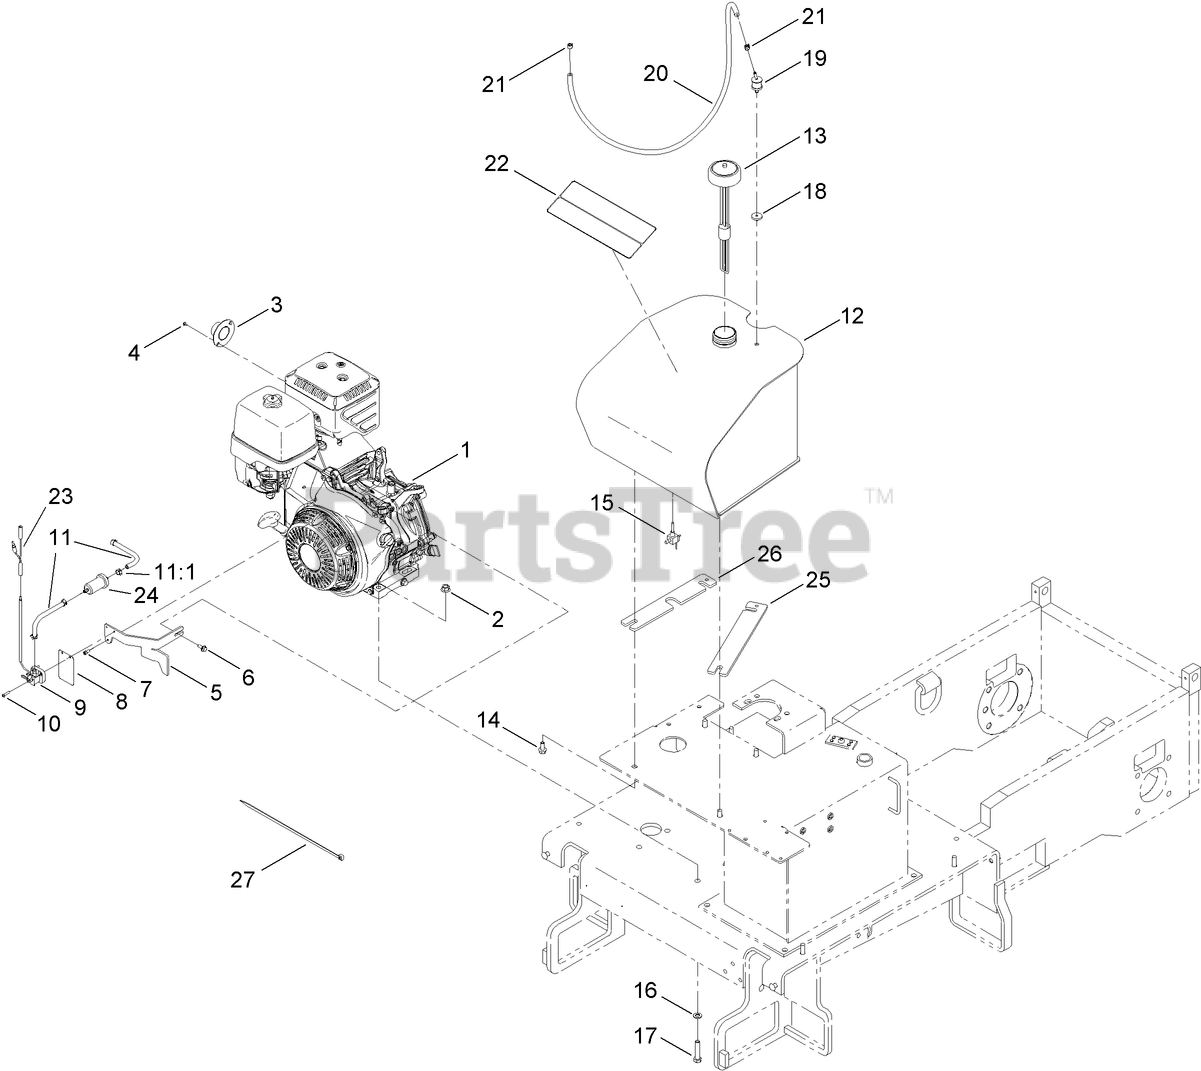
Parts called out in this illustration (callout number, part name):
1	ENGINE-HONDA, GX390
2	NUT-HF
3	DEFLECTOR-EXHAUST
4	SCREW-PPHTF
5	BRACKET-SWITCH, STOP FUEL
6	SCREW-HHF
7	SCREW -HSH
8	HANG TAG-RUN, STOP
9	FUEL SHUT OFF VALVE ASM
10	SCREW-HSBH
11	FUEL HOSE KIT
11:1	CLAMP-HOSE
12	TANK-FUEL
13	GAUGE-FUEL
14	SCREW-HHF
15	VALVE-STRAINER
16	WASHER-FLAT
17	SCREW-HH
18	GROMMET-TANK, TOP
19	VALVE-SLOSH
20	HOSE-FUEL
21	CLAMP-HOSE
22	DECAL-OPERATION
23	HARNESS-WIRE, SHUT DOWN T
24	FILTER-FUEL
25	PLATE-TANK STAND OFF
26	PLATE-TANK STAND OFF
27	TIE-PLASTIC
